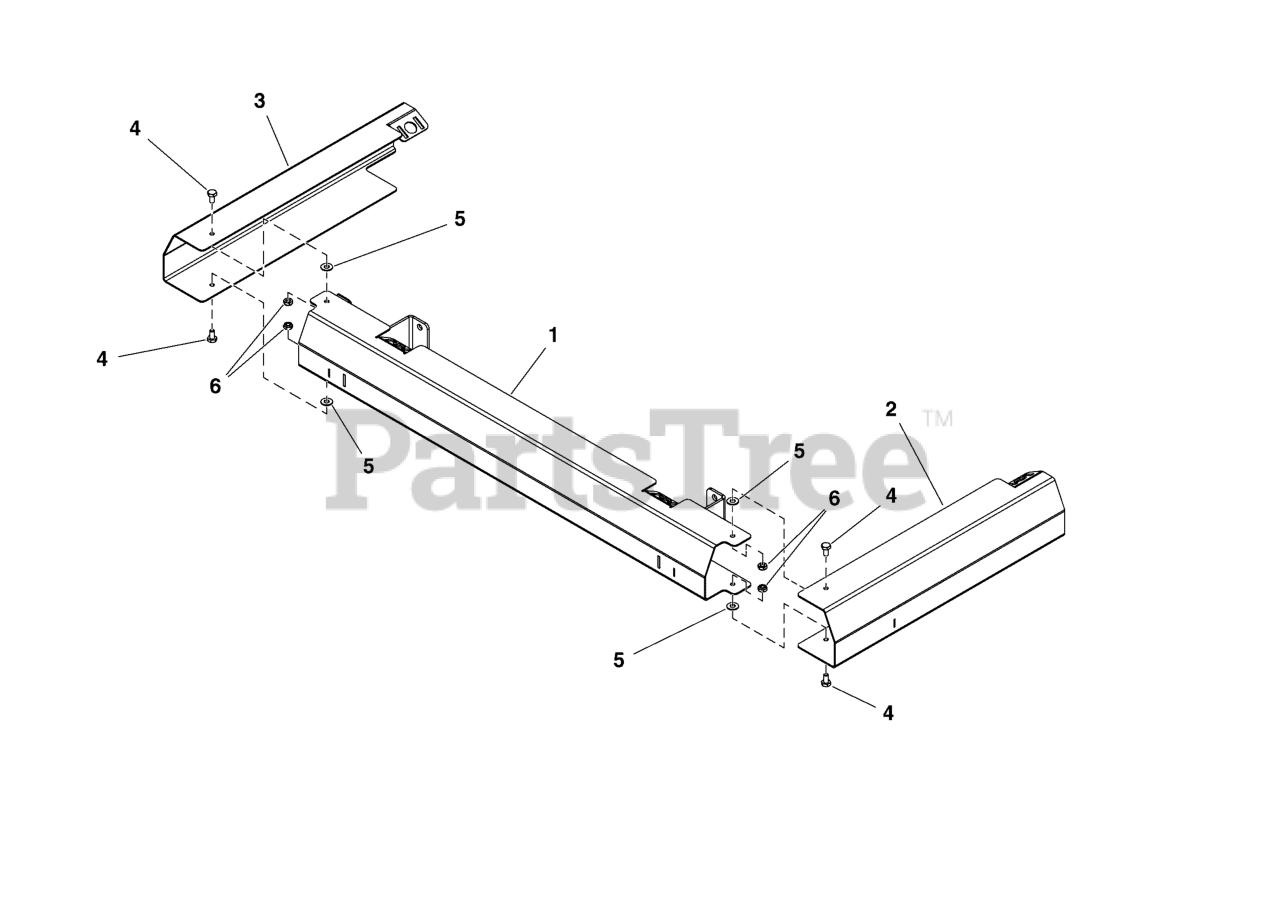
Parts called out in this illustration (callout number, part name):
1	WELD, CENTER, SPRAY BAR, FOLDING BOOMS
2	WELD, LEFT, SPRAY BAR, FOLDING BOOMS
3	WELD, RIGHT, SPRAY BAR, FOLDING BOOMS
4	SCR-CAP, HEX .250"-20 X .500" SS188
5	WSHR-STL, FLT .281" X .625" X .050" IS SS188
6	NUT-HEX-NYLK, .250"-20 TH SS188
